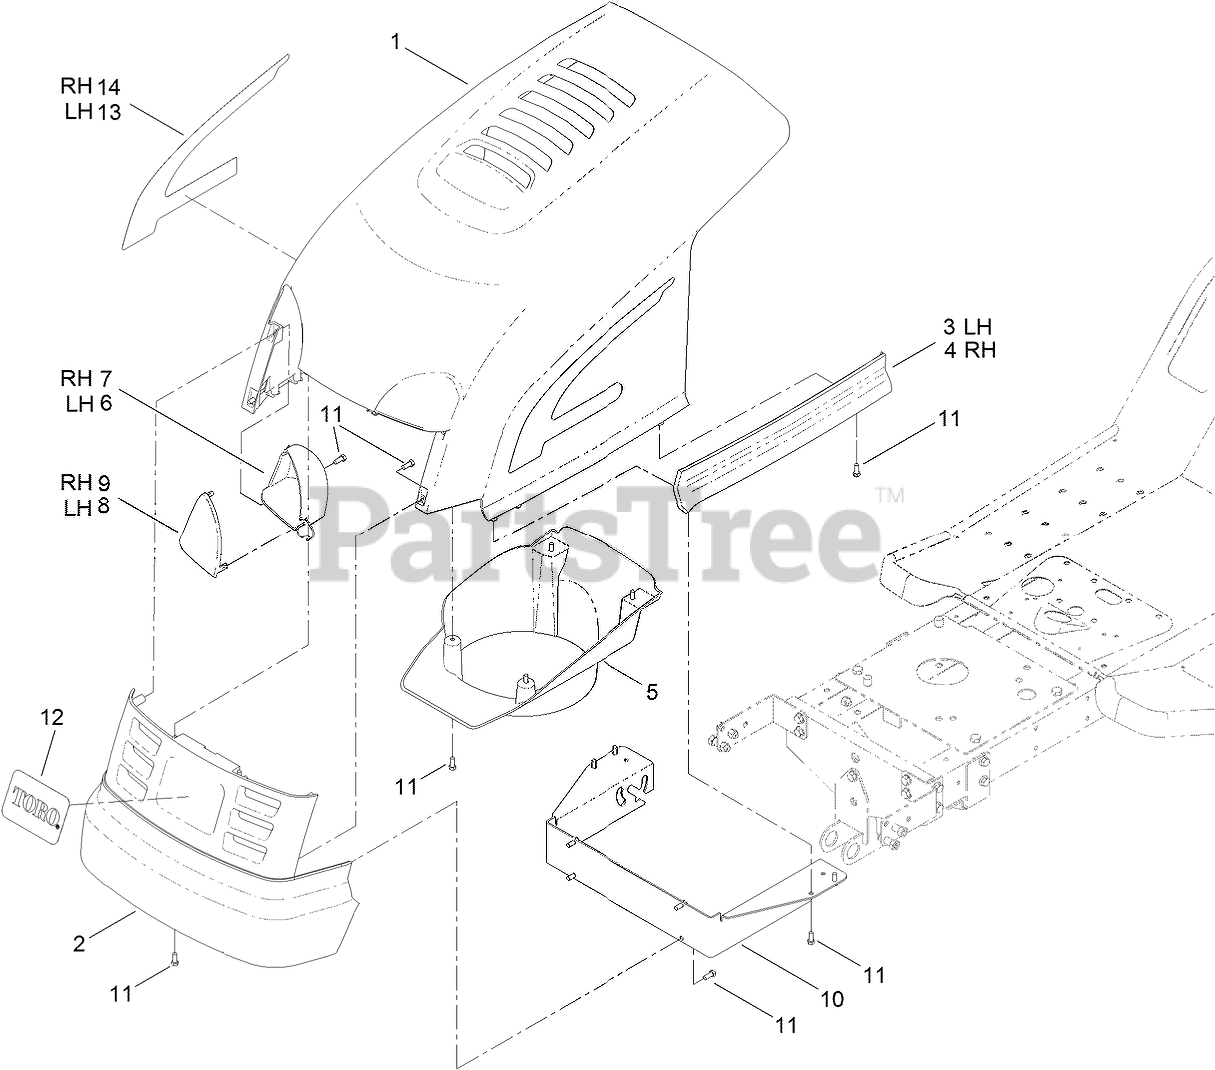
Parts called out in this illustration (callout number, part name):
1	HOOD
3	TRIM-HOOD, LH
4	TRIM-HOOD, RH
5	DUCT-AIR, HOOD
6	REFLECTOR-LH
7	REFLECTOR-RH
8	LENS-LH
9	LENS-RH
10	BRACKET-PIVOT, HOOD
11	SCREW-PLASTITE
13	DECAL-HOOD, LEFT
14	DECAL-HOOD, RIGHT
